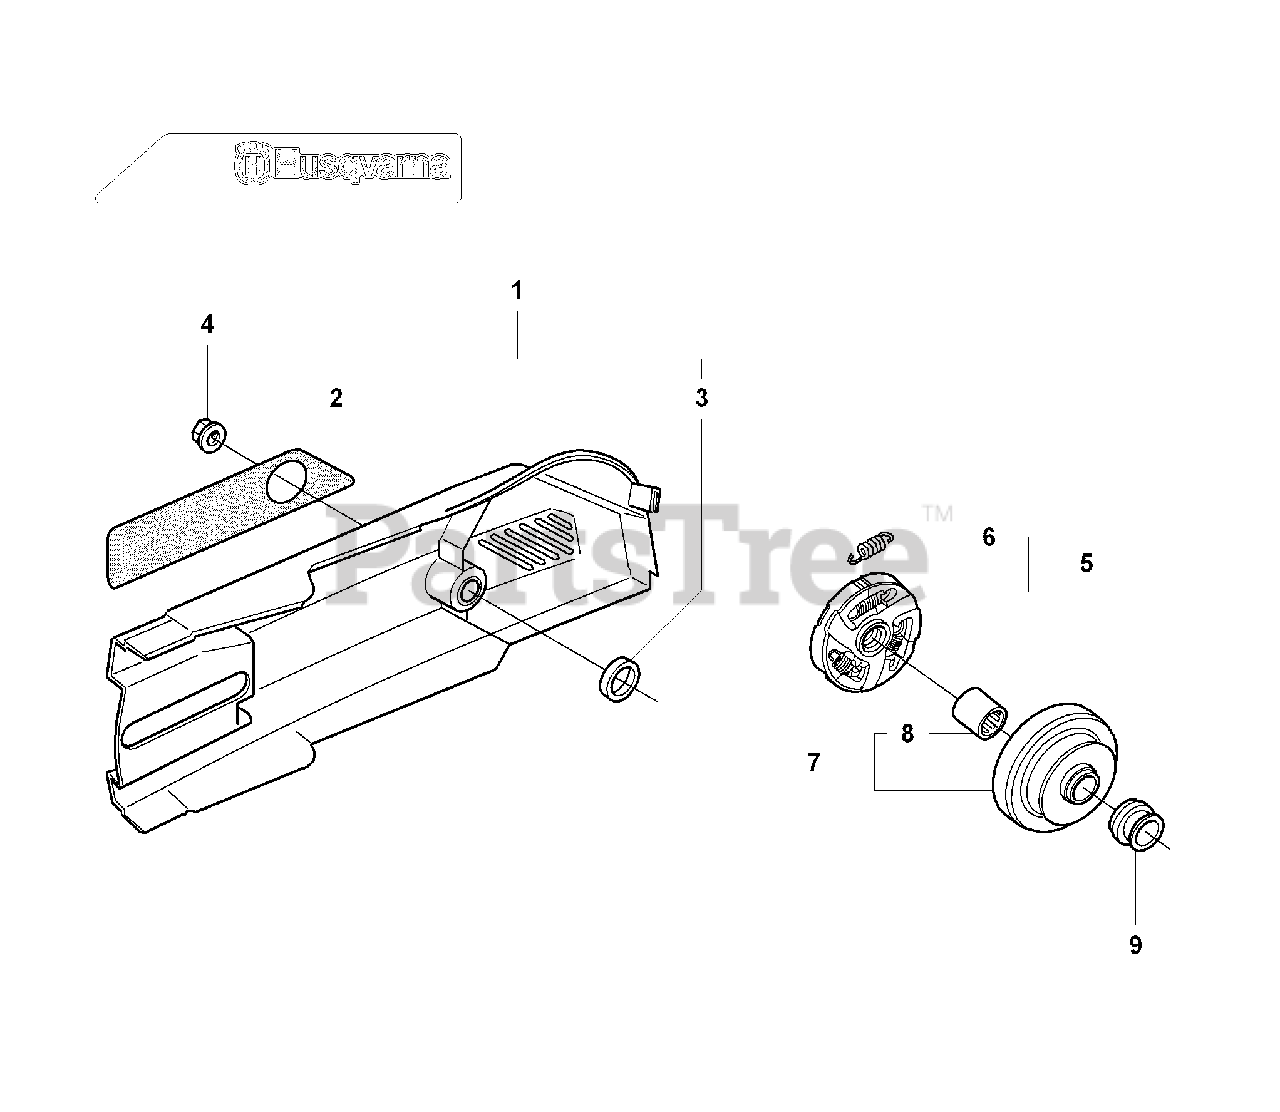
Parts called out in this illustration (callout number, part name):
1	BELT GUARD
3	SPACING SLEEVE
4	NUT FLANGE
5	CLUTCH ASSY
6	CLUTCH SPRING
7	GEAR WHEEL ASSY
8	NEEDLE BEARING
9	SPACING SLEEVE
